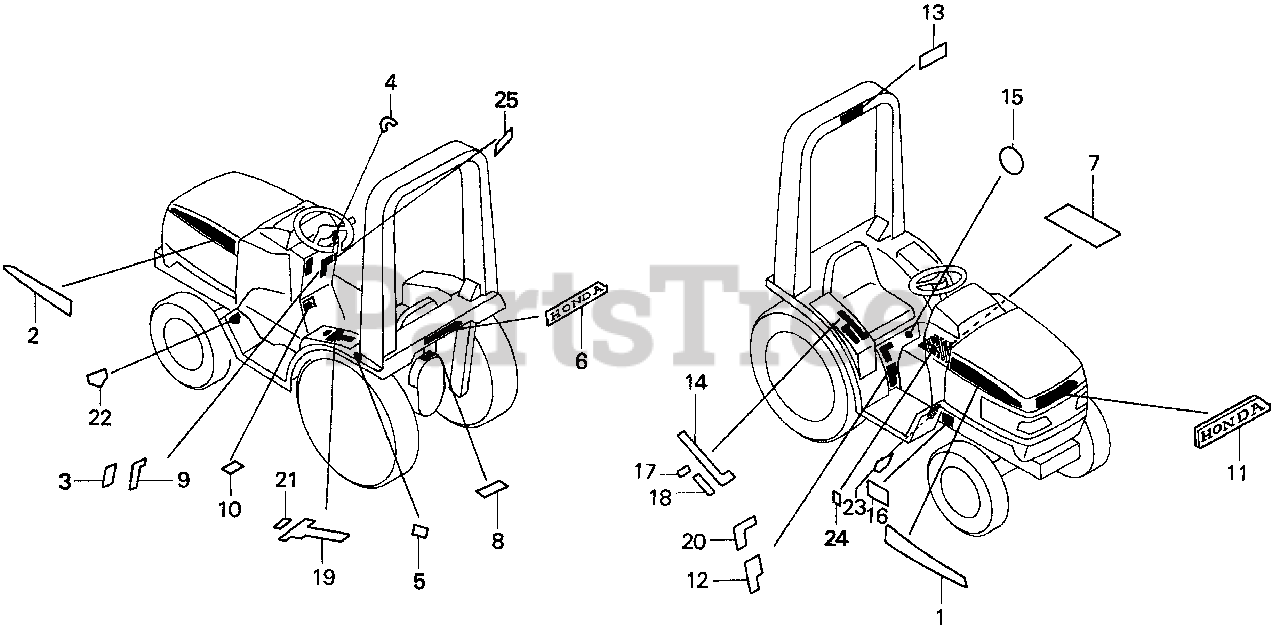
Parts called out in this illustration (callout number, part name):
1	MARK, R. STRIPE
2	MARK, L. STRIPE
3	MARK, COMBINATION SWITCH INDICATION (ENGLISH)
4	MARK, ENGINE SWITCH OPERATION (ENGLISH)
5	LABEL, USE FUEL CAUTION (ENGLISH)
6	EMBLEM, RR.
7	LABEL, WARNING (ENGLISH)
8	LABEL B, WARNING (ENGLISH)
9	MARK, BRAKE LOCK OPERATION (ENGLISH)
10	MARK, HOOD INDICATION
11	EMBLEM, HOOD
12	LABEL, DIFFERENTIAL LOCK CAUTION (ENGLISH)
13	LABEL, ROPS. WARNING (ENGLISH)
14	MARK, LIFT INDICATION (ENGLISH)
15	MARK, SLOW RETURN OPERATION
16	LABEL, OIL CAUTION (E)
17	MARK A, MAIN CHANGE INDICATION (ENGLISH)
18	MARK B, MAIN CHANGE INDICATION
19	MARK, SUB-CHANGE INDICATION (ENGLISH)
21	MARK, OWNER'S MANUAL OPERATION (ENGLISH)
22	MARK, CLUTCH INDICATION (ENGLISH)
23	MARK, BRAKE INDICATION (ENGLISH)
24	MARK, AUXILIARY P.T.O. INDICATION (ENGLISH)
25	MARK, STATIONARY INDICATION (ENGLISH)
